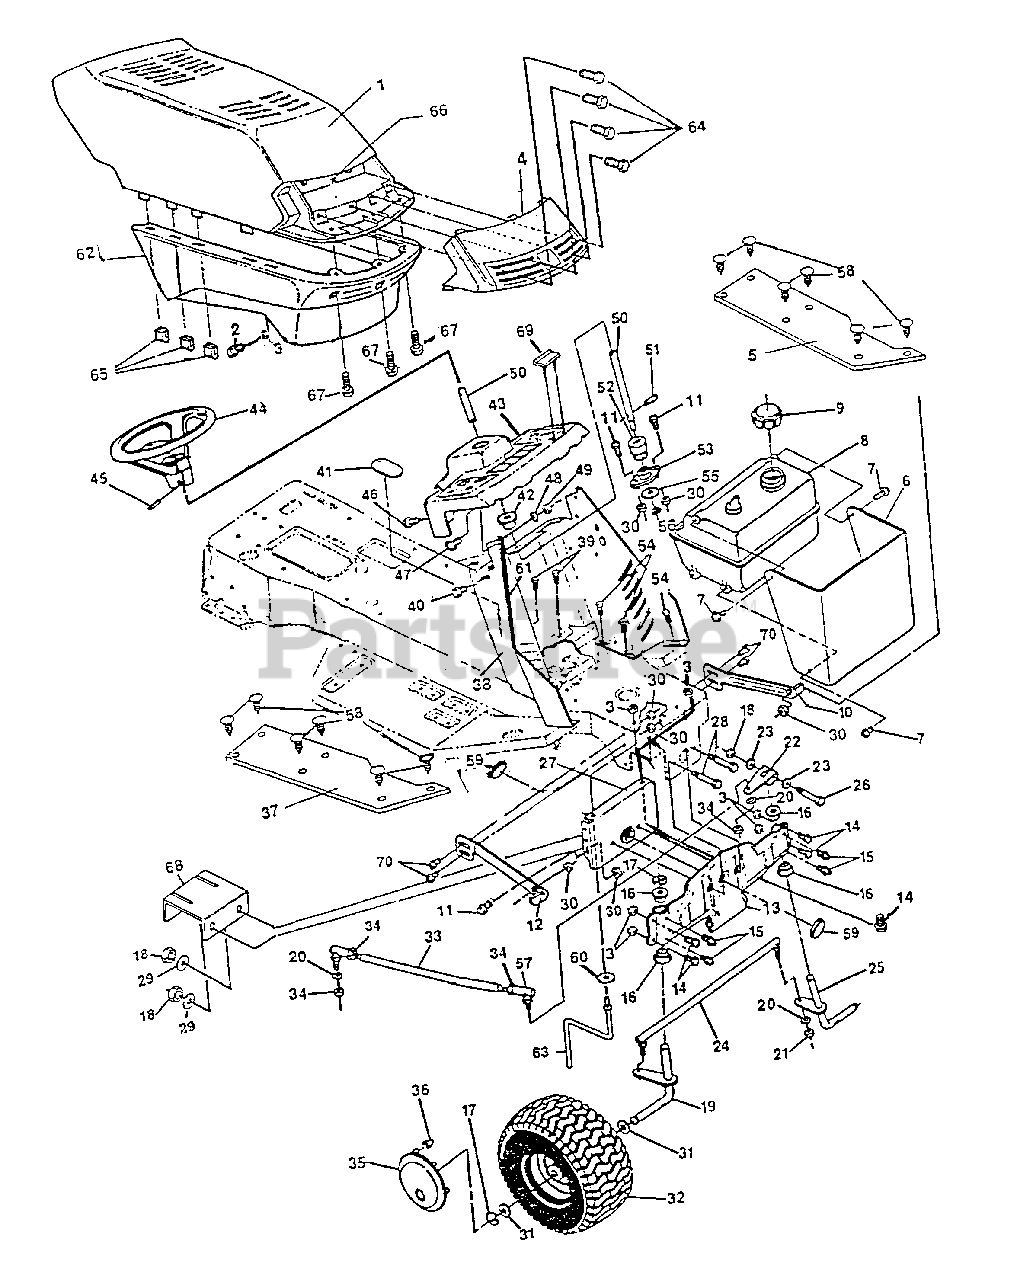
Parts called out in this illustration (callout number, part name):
1	Hood
2	Shoulder Bolt, 5/16-18 Thd.
3	Nut, Hx, Ctrlk, 5/16-18 Thd.
4	Lens, Headlight
5	Assembly, Foot Pad L.H.
6	Heat Shield
7	Screw, Hx Hd, Plastite 1/4 x 34
8	Tank, Gas 1.5 W/Sensor
8	Low Fuel Sensor
10	Bracket, Hood L.H.
11	Screw, Hx Hd, Wd Fl 5/16-1 x 3/4 In.
12	Bracket, Hood R.H.
13	Front Axle W/Bearings & Spindles
14	Screw, Hx Hd, 5/16-18 x 5/8 In.
15	Grease Fitting
16	Bearing, Spindle
18	Nut, Hx, Ctrlk, 3/8-16 Thd.
19	Spindle, R.H.
20	Washer, Split, Lock 3/8 In.
21	Nut, Hex, 3/8-24 Thd.
22	Steering Arm, Upper
23	Washer, Flat, 25/64 In
24	Assembly, Tie Rod
25	Spindle, L.H.
26	Screw, Hx Hd, 3/8-16 x 2-1/2 In.
27	Support Bracket, Front Axle
28	Screw, Hx Hd, 3/8-16 x 3 In.
29	Washer, Spring
30	Nut, Hx, Wd Fl Lk, 5/16-18 Thd.
31	Washer, Flat, 3/4 In.
32	Wheel & Tire Assembly, Front
32	Tire, 20X2OX8
32	Valve Stem
34	Nut, Hx, Jam, 3/8-24 Thd.
35	Hubcap, Front
36	Clip, Hubcap
37	Assembly, Foot Pad R.H.
38	Dash, Lower
39	Screw, Tap, 5/16-18 x 3/8 In
40	Screw, Self-Tap, 1/4-20x 1/2 In
42	Bushing, Upper Steering
43	Dash, Upper
44	Steering Wheel
45	Pin, Spring, 1/4 x 2 In.
46	Screw, Tap, 1/4-20 x 1/2 In.
47	Screw, Hx Hd, 1/4-20 x 5/8 In.
48	Washer, Flat, 9/32 In.
49	Nut, Hx, Ctrlk, 1/4-20 Thd.
50	Shaft, Steering5.
51	Pin, Dowel
52	Pinion, Steering
53	Bearing, Flange
54	Screw, 5/16-18x 50 Wahhtap
55	Washer, Flat, 1/2 In
57	Ball, Joint, 3/8 Thd
58	Ratchet Fastener
59	Plug, Front Axle
60	Washer, Internal Tooth
61	Wide Trim 18"
63	Belt Guide
64	Screw, #4-24 x 1/2 In
65	Clip, Tinnerman
66	Decal, Reflector
67	Screw, # 10 x 1/2 In
68	Bracket, Stop
69	Bumper/Hood
70	Screw, Hex Wd Fl, 5/16-18 x 3/4 In.
71	Washer, Internal Tooth
